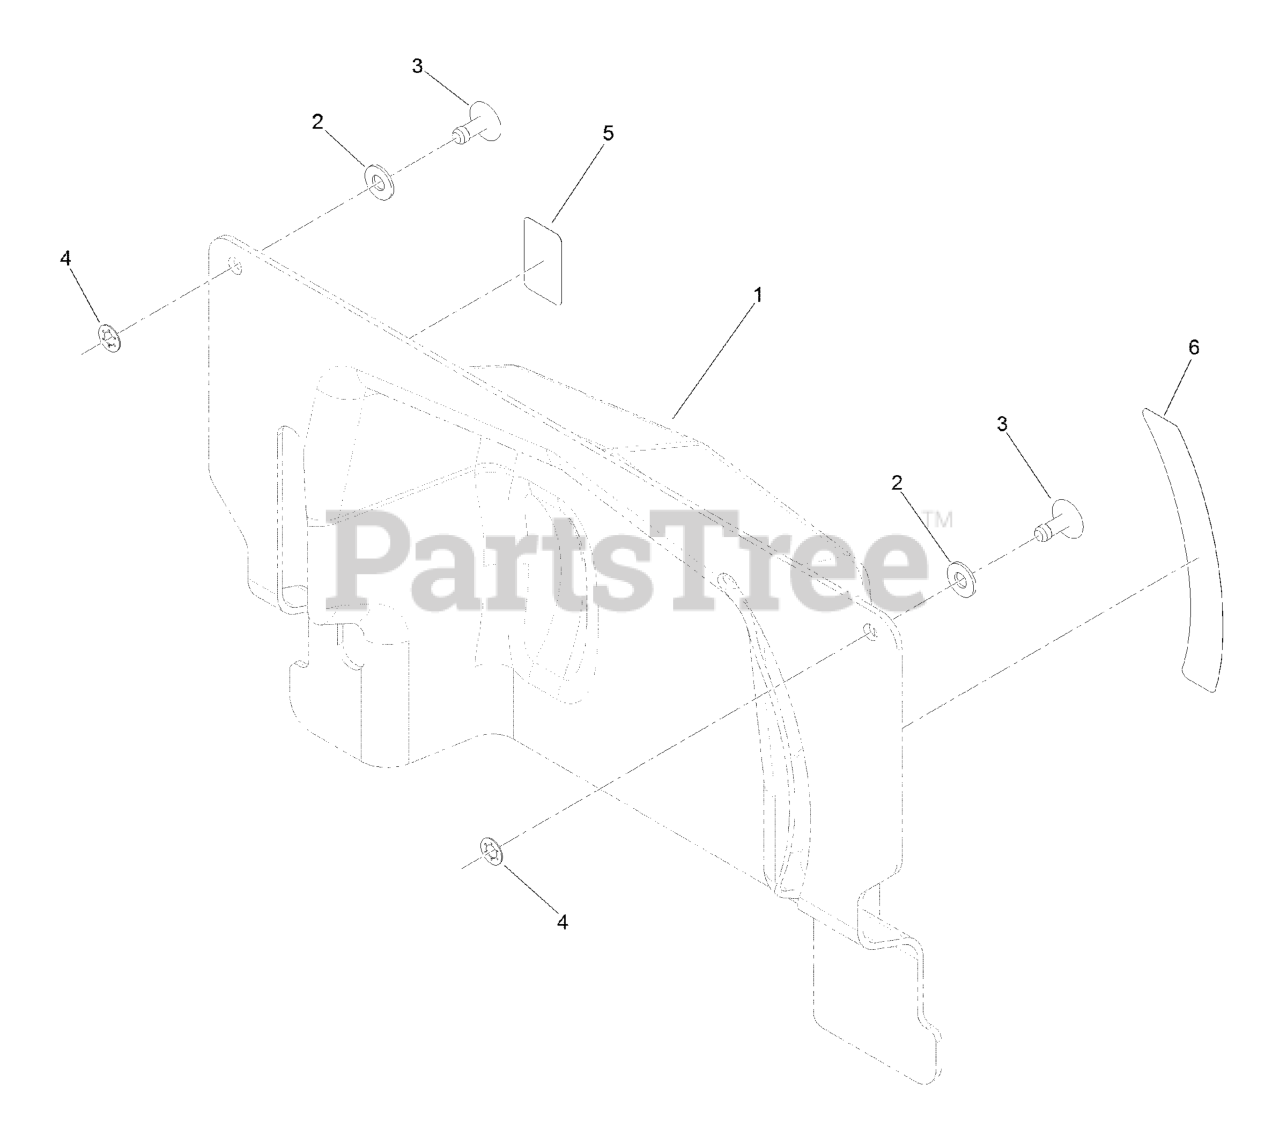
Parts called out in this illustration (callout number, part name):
1	Cover-Transaxle
2	WASHER-FLAT
3	STUD-1/4 TURN
4	RETAINER-STUD
5	DECAL-BRAKE, PARK
6	DECAL-RELEASE, DRIVE
